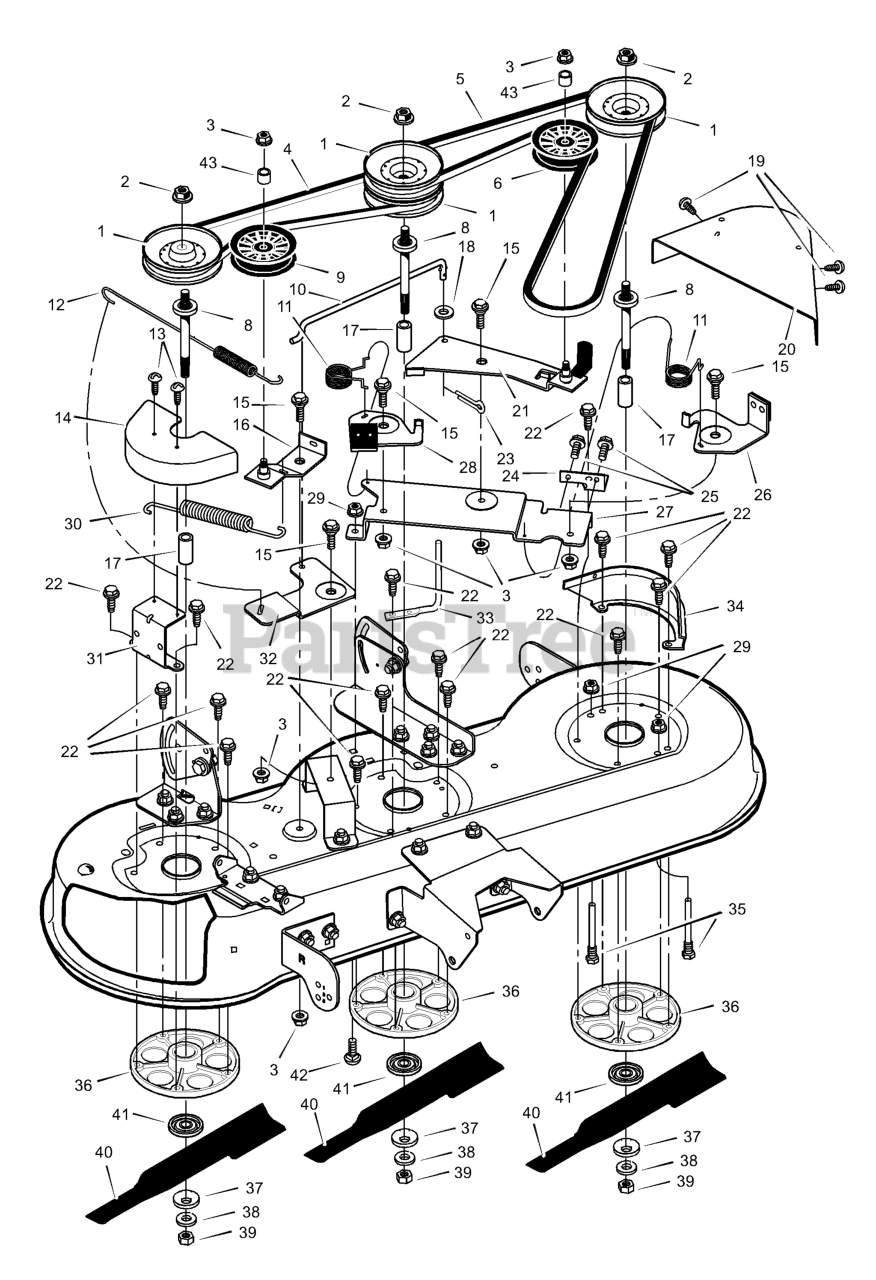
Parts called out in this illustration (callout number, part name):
1	Pulley
3	Nut
4	Belt, Secondary
5	Belt, Primary
6	Pulley, Idler
8	Jackshaft
9	Pulley, Idler
10	Link, Bell Crank
13	Screw
14	Cover, Right Pulley
15	Bolt, Shoulder
16	Arm Assembly, Idler
18	Washer
20	Cover, Left Pulley
21	Arm Assembly, Idler
22	Bolt
23	Pin, Cotter
24	Bracket, Brake Plate
26	Brake Assembly, Left
27	Plate, Brake Arm
28	Brake Assembly, Center
29	Nut, Flange
31	Bracket, Cover
32	Bell Crank
33	Guide, Belt
34	Bracket, Pulley Cover
35	Guide, Belt
36	Housing, Jackshaft
39	Nut, Blade
41	Adapter, Blade
42	Bolt, Carriage
